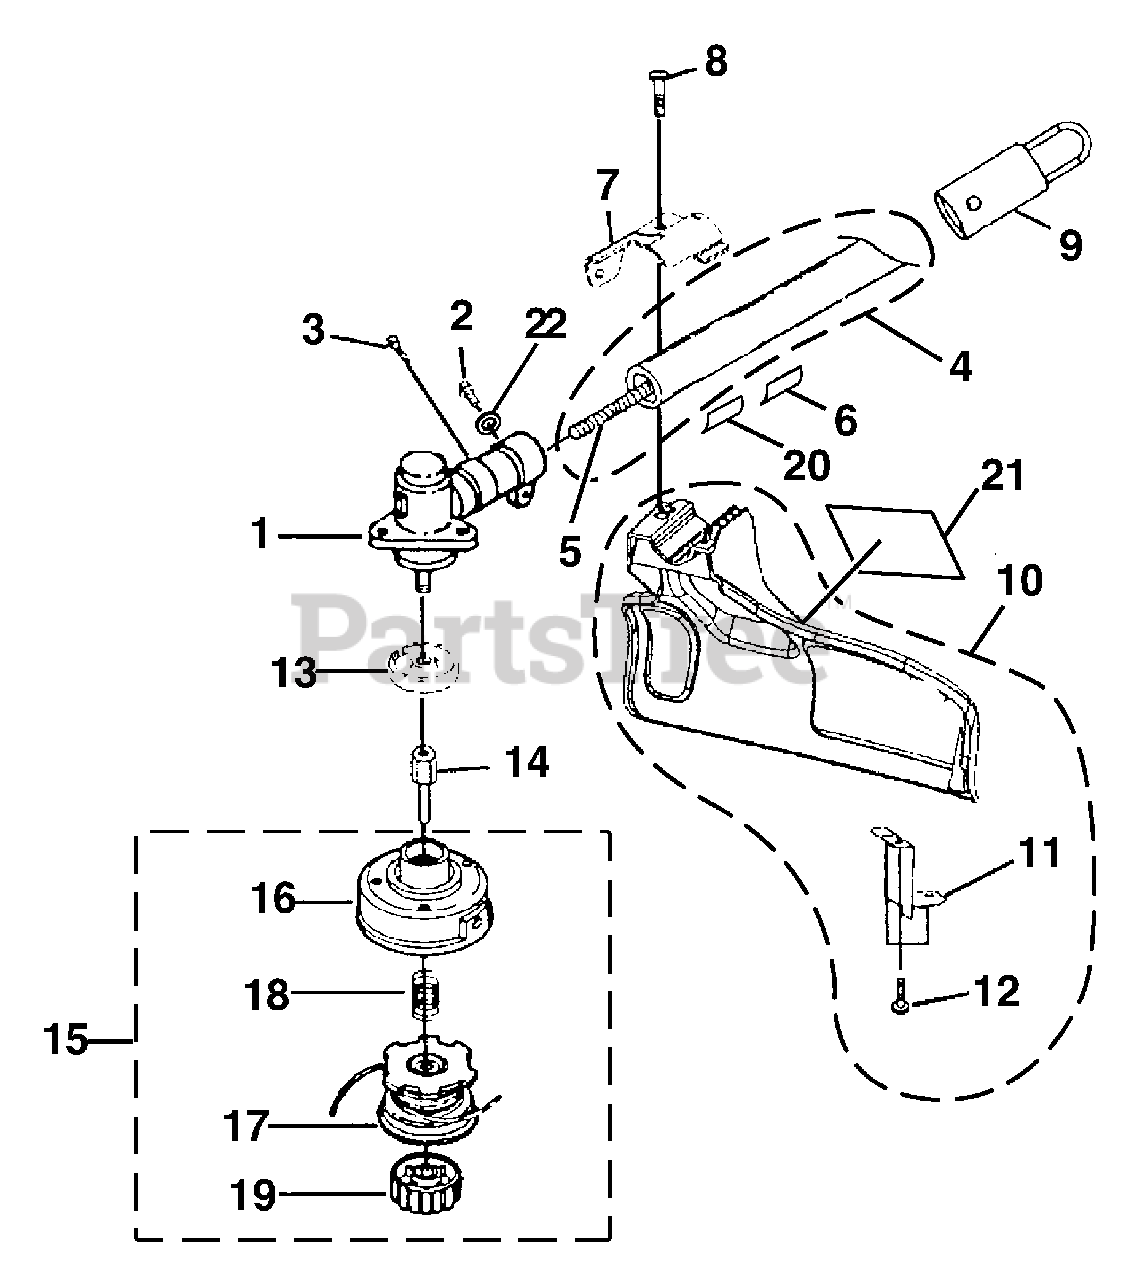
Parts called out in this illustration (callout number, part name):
1	GEAR HEAD ASSEMBLY WITH SCREWS
2	SCREW (M5 x 15 mm HEX HD.)
3	CAP SCREW (M6 x 30 mm)
4	DRIVE SHAFT HOUSING ASSEMBLY
5	FLEXIBLE SHAFT ASSEMBLY
6	WARNING DECAL
7	GRASS SHIELD CLAMP
8	SCREW (M6 x 30 mm)
9	HANGER CAP
10	GRASS SHIELD ASSEMBLY W/SCREWS
11	CUT-OFF BLADE
12	SCREW (M4.2 x 12 mm)
13	FLANGE WASHER
14	STRING HEAD ADAPTER
15	STRING HEAD ASSEMBLY
16	HOUSING W/EYELET
17	SPOOL W/STRING
18	COMPRESSION SPRING
19	SPOOL RETAINER
20	WARNING LABEL
21	LOGO PLATE
